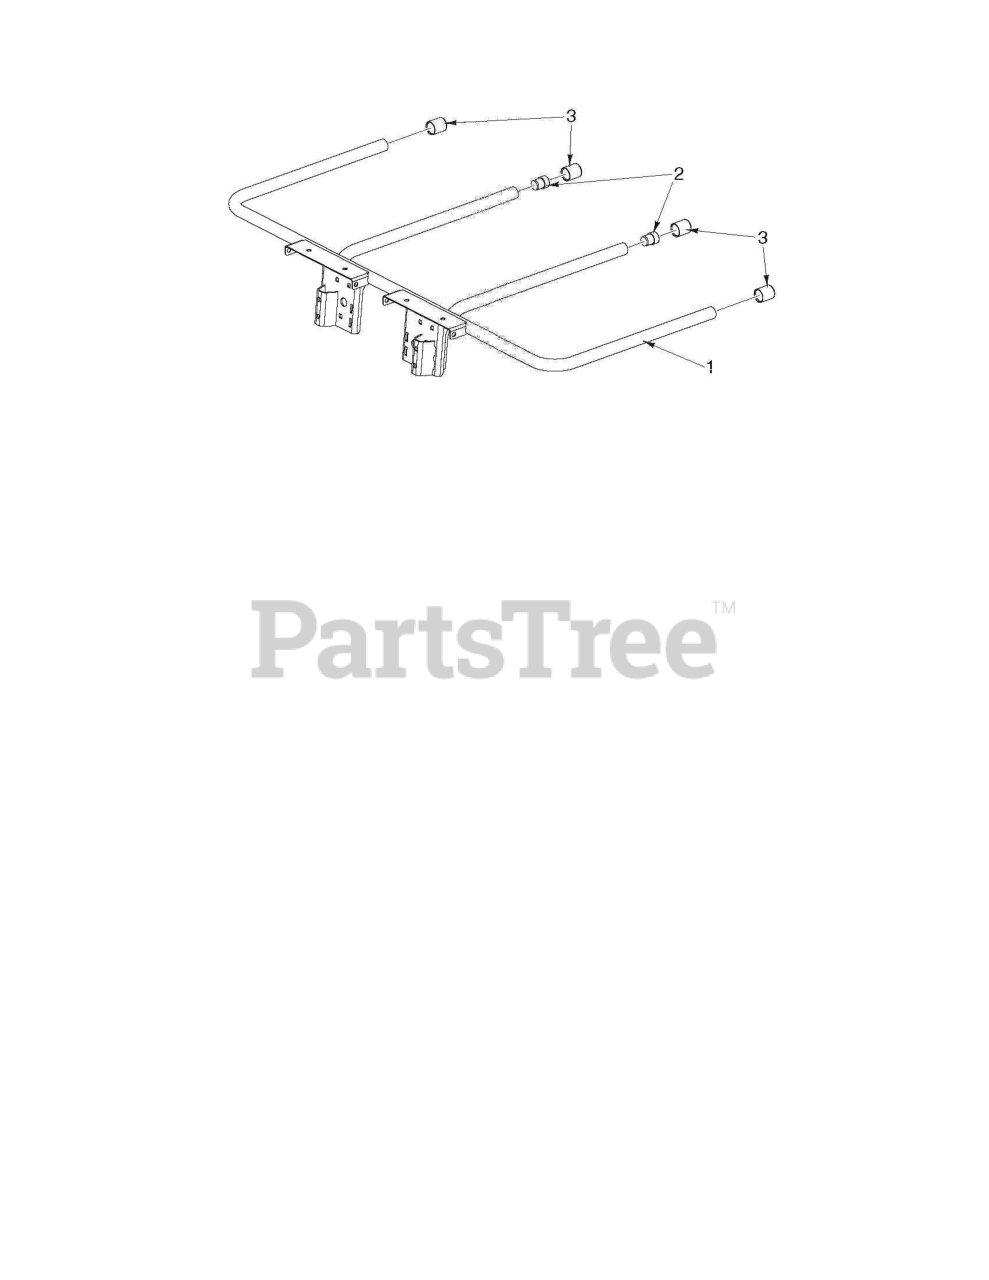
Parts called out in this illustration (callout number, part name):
1	BAGGER.ASM.FRAME.3BIN.BLACK
2	SPACER PLUG, BAGGER
3	PLUG, TUBING END
